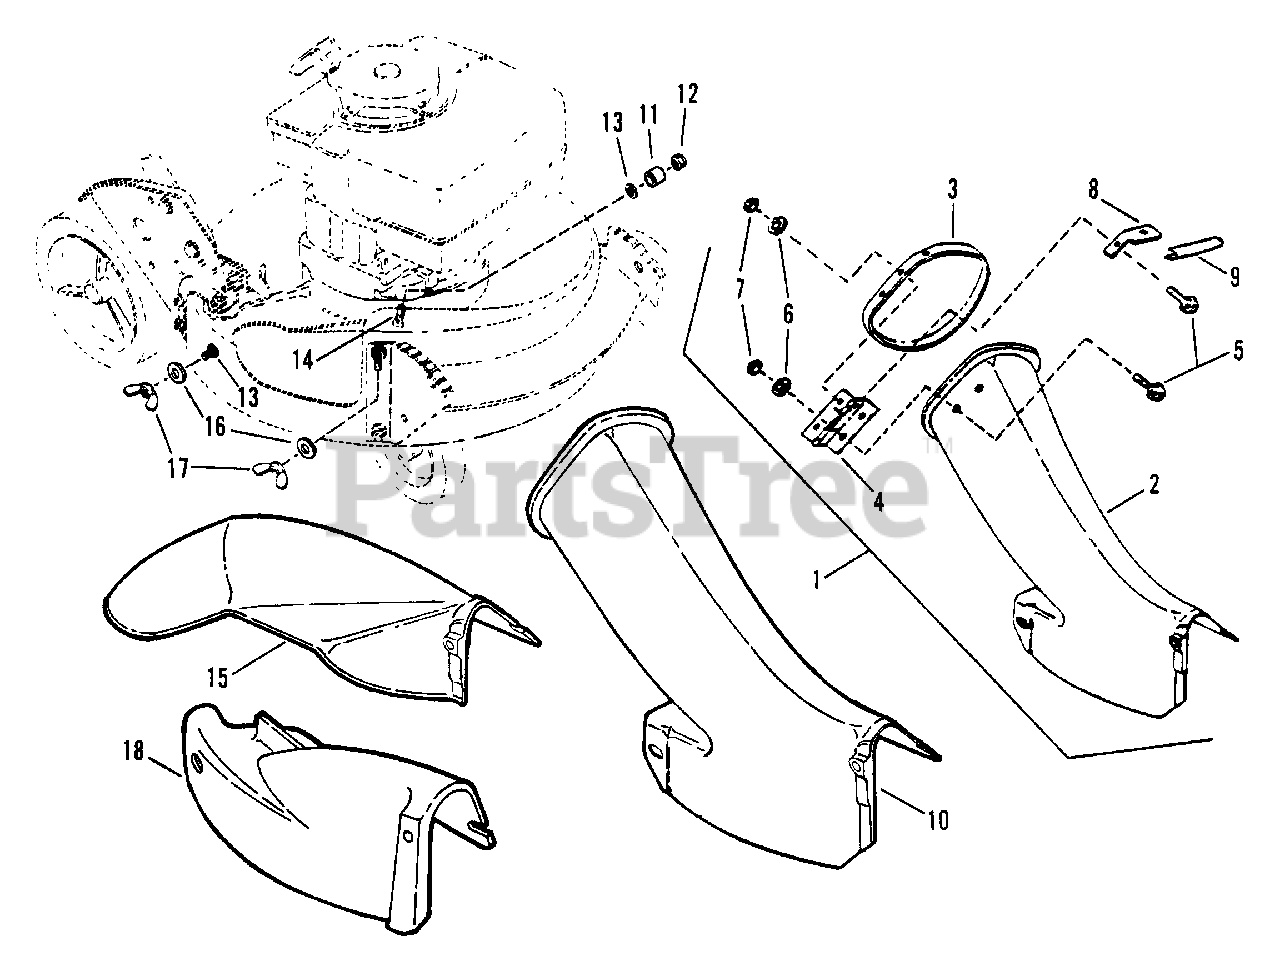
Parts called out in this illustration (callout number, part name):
1	ASSEMBLY, Bag Adapter & Cover
2	ADAPTER, Grass Bag
3	COVER, Bag Adapter
4	HINGE, Chute Cover
5	BOLT, 1/4-20 x 1/2" Short Neck Carriage, Grade 5
6	WASHER, 1/4 Internal Tooth Lock
7	NUT, 1/4-20 Hex, Grade 5
8	STOP, Cover
9	MOLDING, Trim
10	ADAPTER, Grass Bag
11	SPACER
12	NUT, 5/16-18 Hex Flange Center Lock
13	RETAINER, 5/16 Bolt
14	BOLT, 5/16-18 x 3/4" Short Neck Carriage, Grade 5
15	KIT, Side Chute
16	WASHER, 5/16 Flat
17	WING-NUT, 5/16-18 Nyloc
18	COVER, 21" Deck
